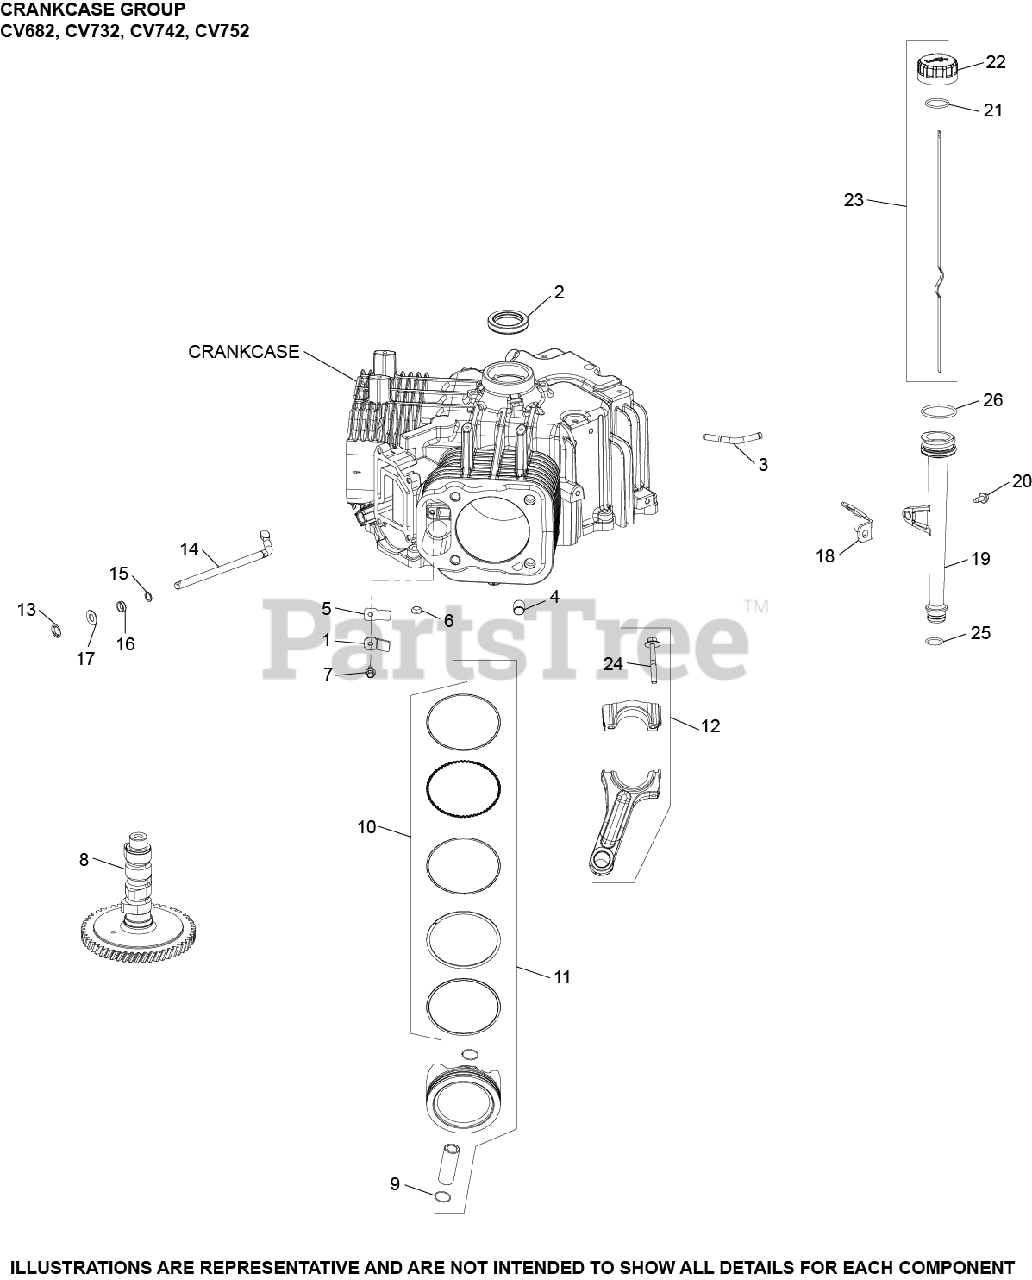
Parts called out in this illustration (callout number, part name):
1	RETAINER, BREATHER REED
2	SEAL, OIL (HELIX LIP)
4	PIN, LOCATING
5	REED, BREATHER
6	PLUG, CUP
7	SCREW, FLG THD FRM M5X.8X10
8	KIT, CAMSHAFT
9	RETAINER, PISTON PIN
10	RING SET(STD)STYLE B-1.2mm Tp RING THICK
10	RING SET(.08)STYLE B-1.2mm Tp RING THICK
10	RING SET(.25)STYLE B-1.2mm Tp RING THICK
10	RING SET(.50)STYLE B-1.2mm Tp RING THICK
11	PISTON W/RINGS (STYLE B)(STD) - RING SET 25 108 01-S
11	PISTON W/RINGS (STYLE B)(.08) - RING SET 25 108 02-S
11	PISTON W/RINGS (STYLE B)(.25) - RING SET 25 108 03-S
11	PISTON W/RINGS (STYLE B)(.50) - RING SET 25 108 04-S
12	KIT, CONNECTING ROD ASSEMBLY USE 25 067 04-S
13	RETAINER, RING
14	SHAFT, GOVERNOR CROSS
15	WASHER, FLAT 11/32"
16	SEAL, GOVERNOR CROSS SHAFT
17	WASHER, FLAT 9 MM
18	BRACKET, OIL FILL TUBE USE 24 126 243-S
19	TUBE ASSEMBLY
20	SCREW, FLG THD FRM M5X0.8X13
21	O-RING, DIPSTICK
22	KIT, OIL FILL CAP (YELLOW)
23	DIPSTICK, ASSY
24	KIT, ROD BOLTS
25	O-RING, LOWER OIL FILL TUBE
26	O-RING, UPPER OIL FILL TUBE
